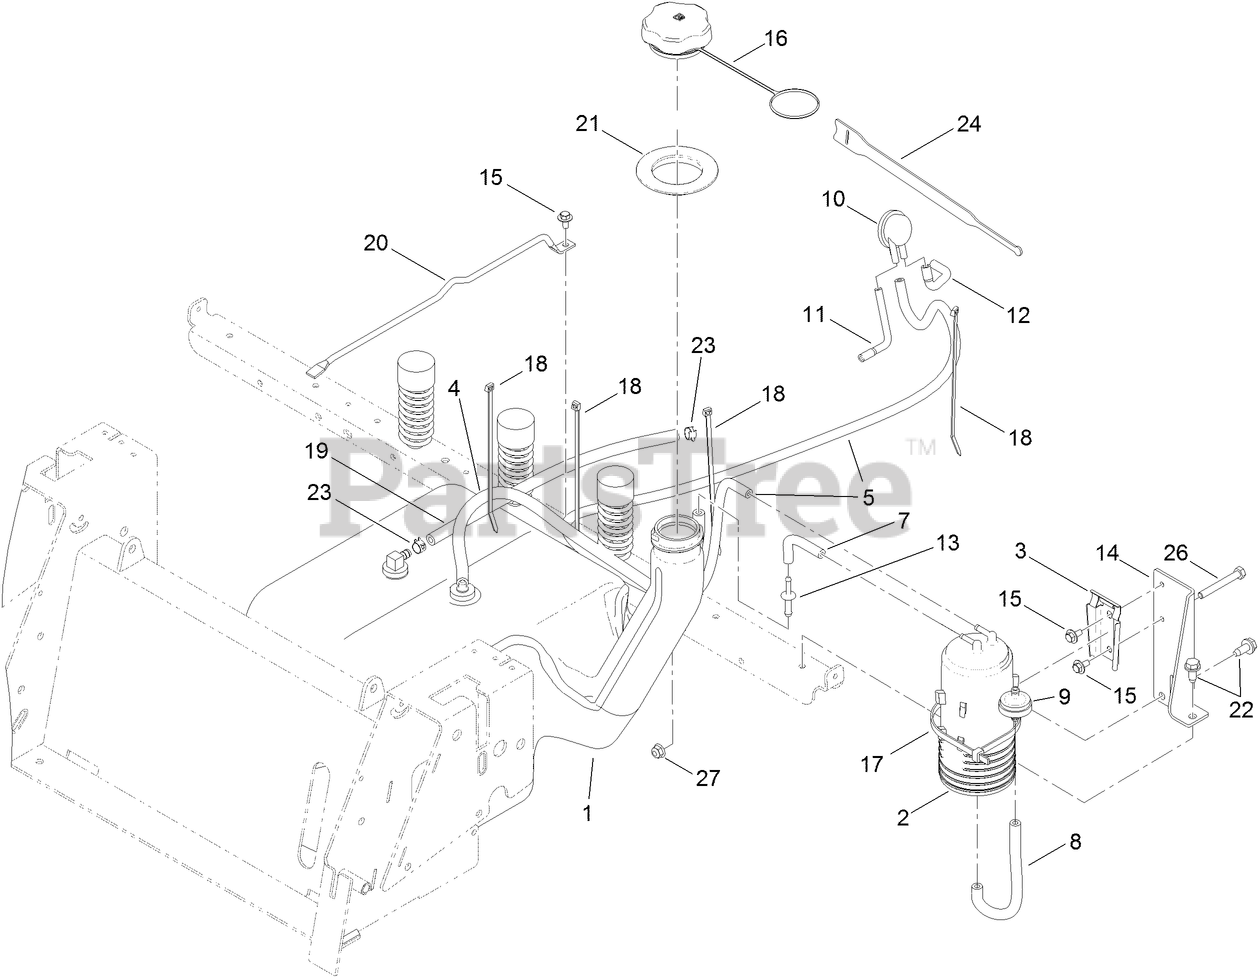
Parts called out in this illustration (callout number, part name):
1	FUEL TANK ASM
2	CANISTER-CARBON, 800CC
3	BRACKET-CANISTER, CARBON
4	HOSE-FUEL
5	HOSE-FUEL
7	HOSE-FUEL
8	HOSE-FUEL
9	FILTER-FUEL, INLINE
10	VALVE-CONTROL, VACUUM
11	HOSE-VENT, FORMED
12	HOSE-VENT, FORMED
13	ADAPTER-ORIFICE
14	BRACKET-CANISTER
15	SCREW-HHFTF
16	CAP-FUEL
17	TIE-CABLE
18	TIE-CABLE
19	HOSE-FUEL
20	ROD-TANK, GAS
21	SEAL-TANK
22	SCREW-HWHTF
23	CLAMP-HOSE
24	STRAP-VELCRO, CABLE TIE
26	SCREW-HH
27	NUT-HF, NI
